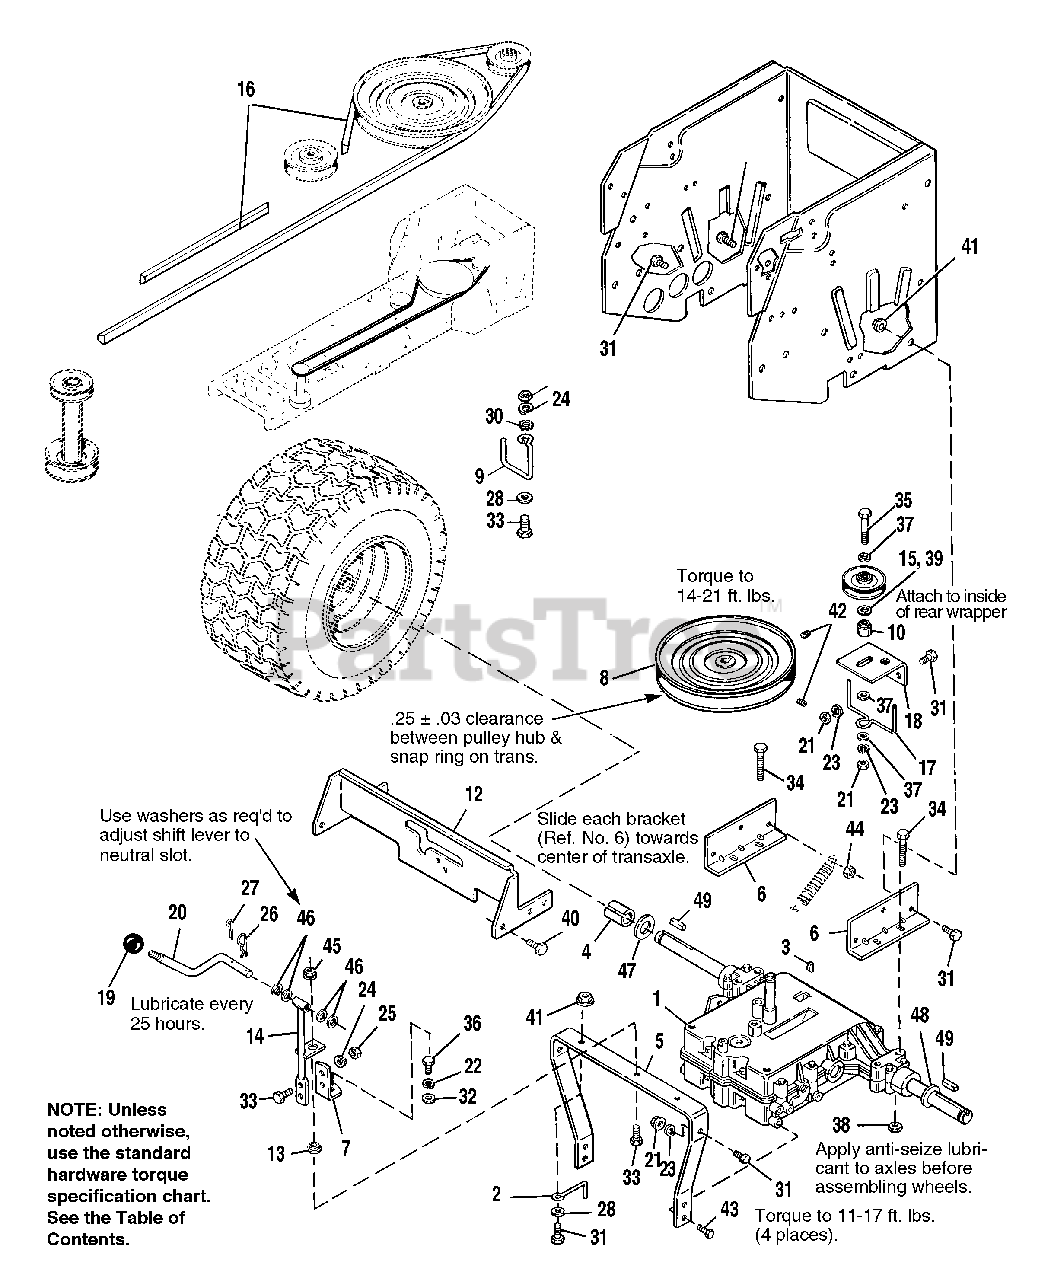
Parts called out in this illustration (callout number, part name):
3	KEY, Woodruff, #9
5	SUPPORT, Transmission, Front
6	SUPPORT, Transmission, Rear
7	LINK, Shift, Lower
8	PULLEY ASSY., Transmission
12	QUADRANT, Shift
13	SPACER
14	SHIFT LINK ASSY., Upper
15	PULLEY, Idler, "V"
18	BRACKET, Pulley
19	KNOB, Ball, Shift
21	NUT, Hex, 3/8-16
22	LOCKWASHER, 1/4
23	LOCKWASHER, 3/8
24	LOCKWASHER, 5/16
25	NUT, Hex, 5/16-18
26	PIN, Quick
27	PIN, Cotter
28	WASHER, 11/32
30	LOCKWASHER, Ext.
31	CAPSCREW, Hex 3/8-16 x 1
32	WASHER, Plain
33	CAPSCREW, Hex, 5/16-18 x 1
34	CAPSCREW, Hex, 5/16-18 x 2-1/2
35	CAPSCREW, 3/8-16 x 2-3/4
36	CAPSCREW, Hex, 1/4-28 x 5/8
37	WASHER
38	LOCKNUT, 5/16-18
39	WASHER, 13/32
40	SCREW, Taptite, 1/4-20 x 3/8
41	LOCKNUT, Hex, Flange, 3/8-16
42	SETSCREW, 5/16-18 x 5/8
43	SCREW, Taptite, 5/16-18 x 5/8
44	LOCKNUT, Hex, 3/8-16
45	NUT, Hex, Flange Hd., 5/16-18
46	WASHER, Rev. Pinion
47	WASHER
48	WASHER, 1/4
49	KEY, 3/16 x 3/16 x 1-1/2
